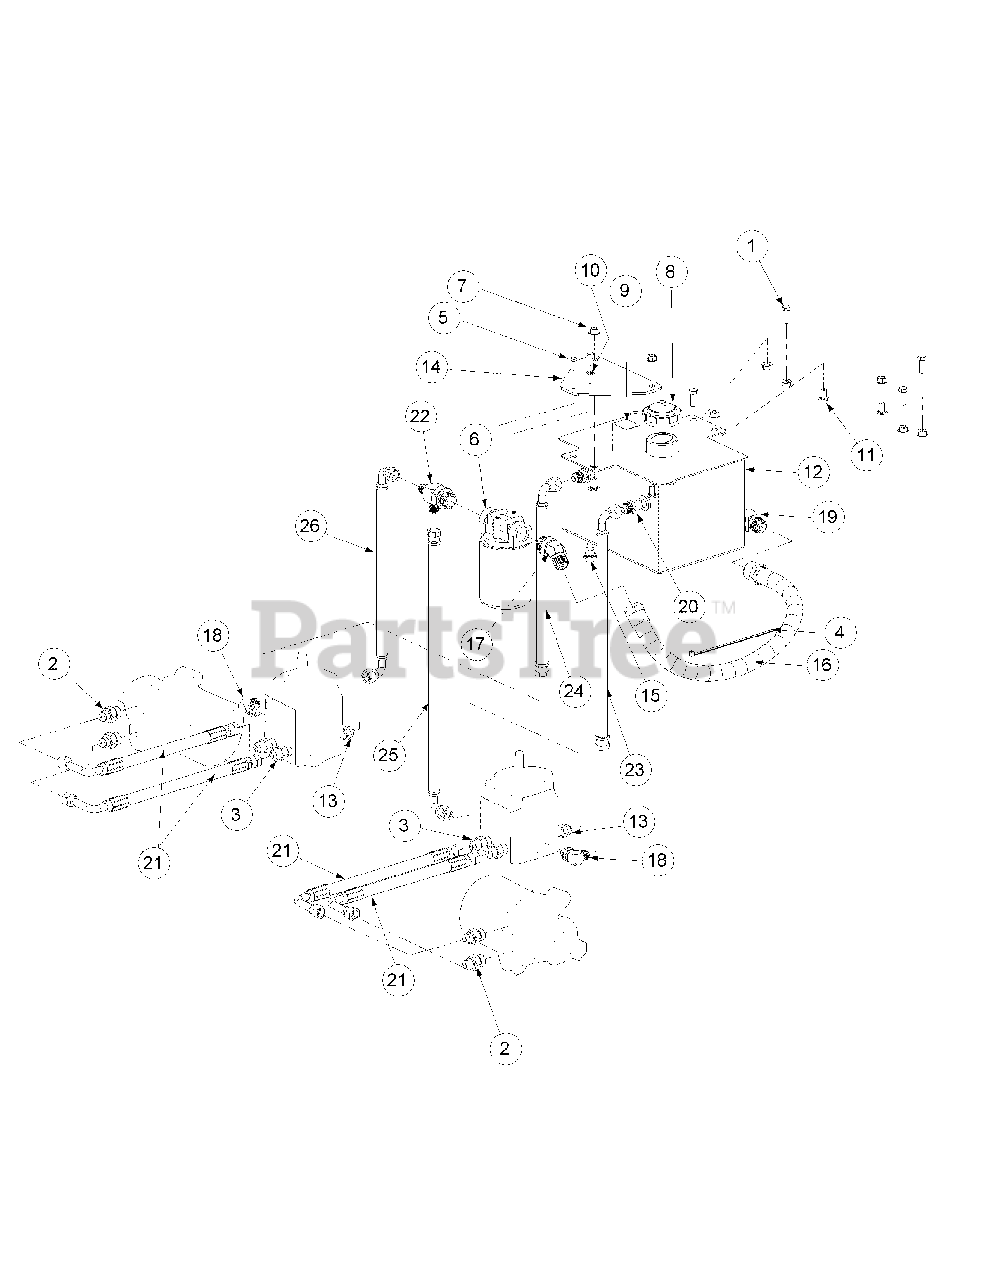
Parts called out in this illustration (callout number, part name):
1	Hex Cap Screw, 3/8-16, 1
2	Fitting 1/2 x 3/4 - O Ring
3	Fitting 1/2 x 1/2 - O Ring to Flare
4	Cable Tie, 3/16 x .05 x 7.4
5	Hex Cap Screw, 1/4-20, .75
6	Filter Head 3/4 includes:
7	Hex Nut Flange Lock, 3/8-16
8	Cap, Hydro Oil Tank
9	Decal Oil Only 15W40
10	Lock Washer, 1/4
11	Carriage Bolt, 3/8-16 x .75 LG.
12	Hydraulic Tank Assembly
13	Fitting Connector, 1/2 x 3/8
14	Oil Filter Mounting Plate
15	Oil Pan Drain Plug w/ Seal
16	Tank to Filter Hose Assembly
17	Fitting, 3/4 x3/4 x 45 degree
18	Elbow Fitting, 3/8 O-ring, 1/2 Flare
19	Fitting Elbow, 1/2 x 1/2
20	Fitting, 3/8 NPT, 1/2 Flare
21	Long Pressure Hose Assembly
22	Tee Fitting, 3/4 x 1/2 x 1/2
23	17.75" Return Hose Assembly, RH
24	14.25" Return Hose Assembly, LH
25	21.25" Supply Hose Assembly, RH
26	15.50" SupplyHose Assembly, LH
